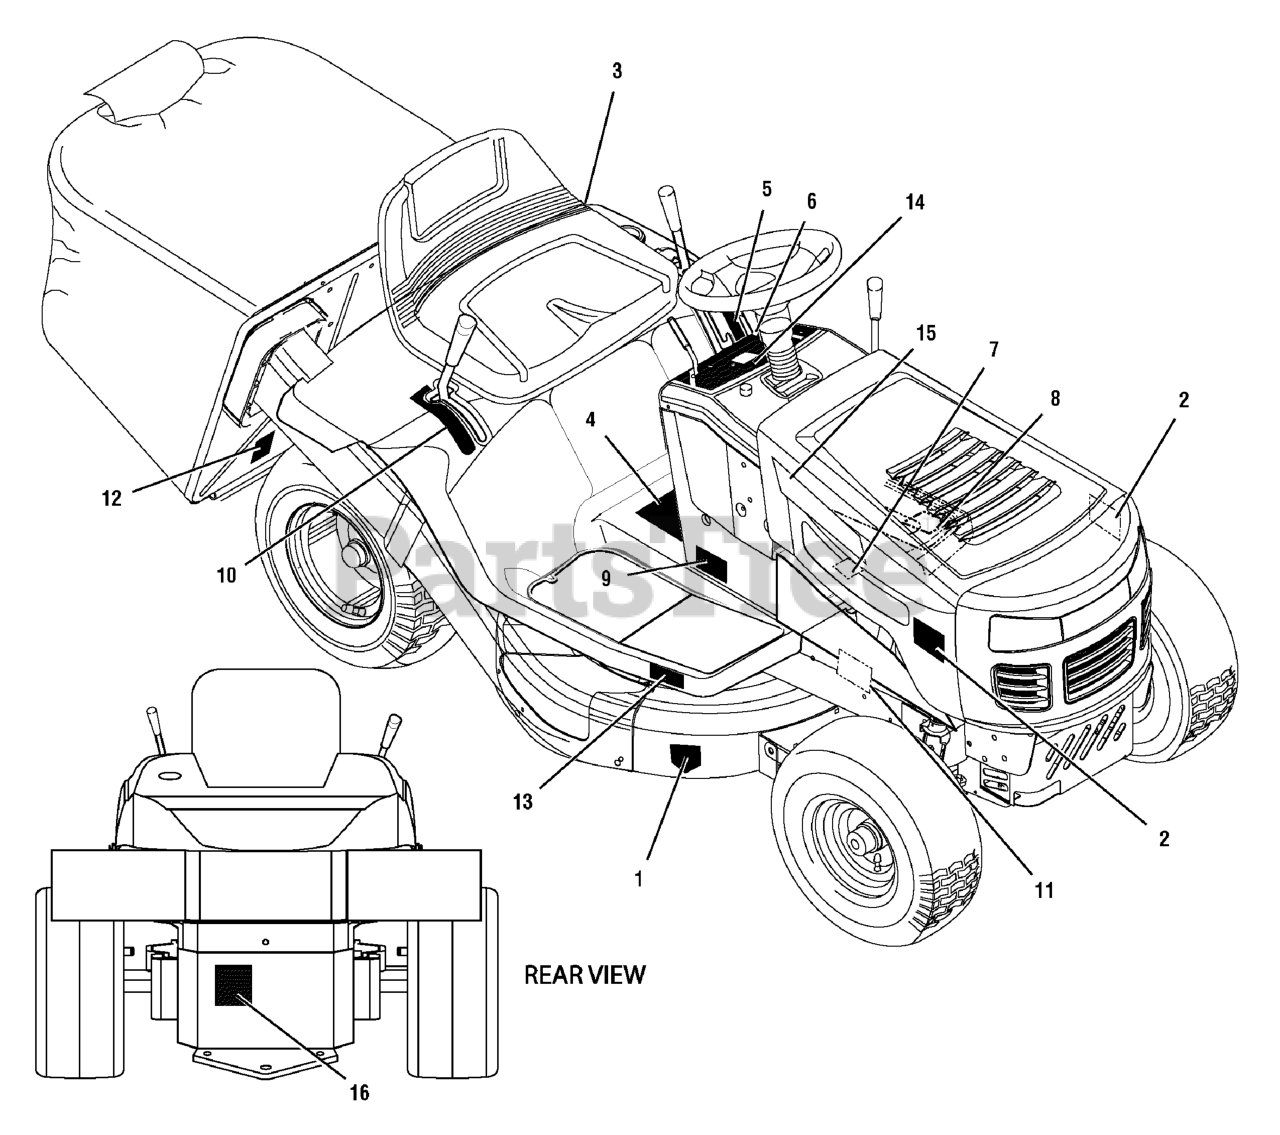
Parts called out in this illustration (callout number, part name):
1	DECAL, Cut Fingers Signal
2	DECAL, 145/76, Black, Red, White
3	DECAL, Gas
4	DECAL, Warning Export
5	DECAL, 7 Position Cut Height
6	DECAL, Deck Level
7	DECAL, No Step Export
8	DECAL, Brake/Clutch Export
9	DECAL, B&S Logo
10	DECAL, 5 Speed
11	DECAL, Heat Shield Warning
12	DECAL, Warning Load Limit Export
13	DECAL, Warning Pinch Point
14	DECAL, Dash Symbols W1
15	DECAL, MURRAY L & R
16	DECAL, 100db Export/Serial Tag Identification
